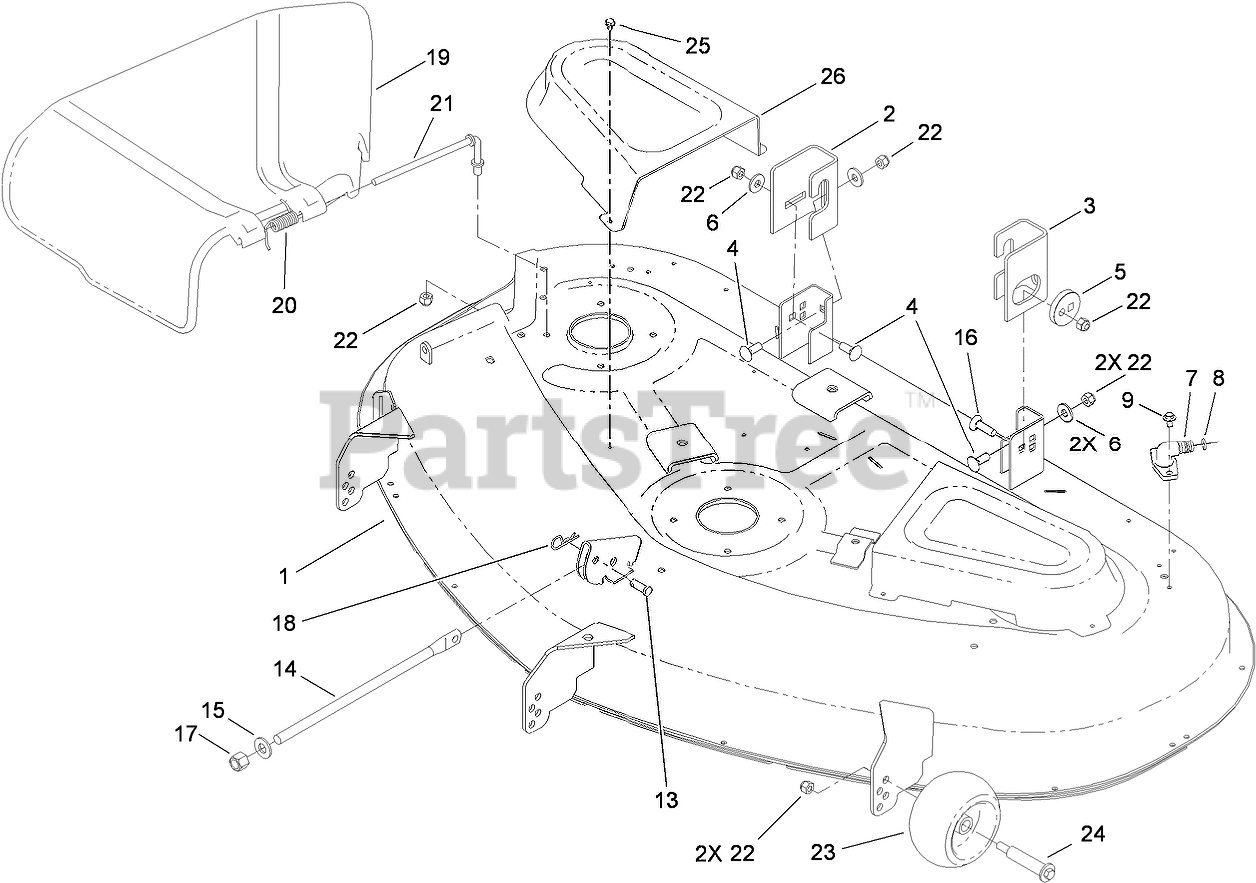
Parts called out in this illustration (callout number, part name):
1	50 INCH DECK ASM
2	BRACKET-HANGER, RIGHT REAR
3	BRACKET-HANGER, LEFT REAR
4	BOLT-CARR
5	ECCENTRIC
6	WASHER-HARDENED
7	FITTING-WASHOUT
8	O-RING
9	SCREW-HHFTF
13	PIN-CLEVIS
14	ROD-LIFT
15	WASHER-THRUST
16	SCREW-CARR
17	NUT-LOCK, NI
18	PIN-HAIR
19	DEFLECTOR
20	SPRING-TORSION
21	ROD-PIVOT
22	NUT-LOCK, NI
23	ROLLER-SCALP, ANTI
24	BOLT-SHOULDER
25	SCREW-HWHTF
26	COVER-BELT
